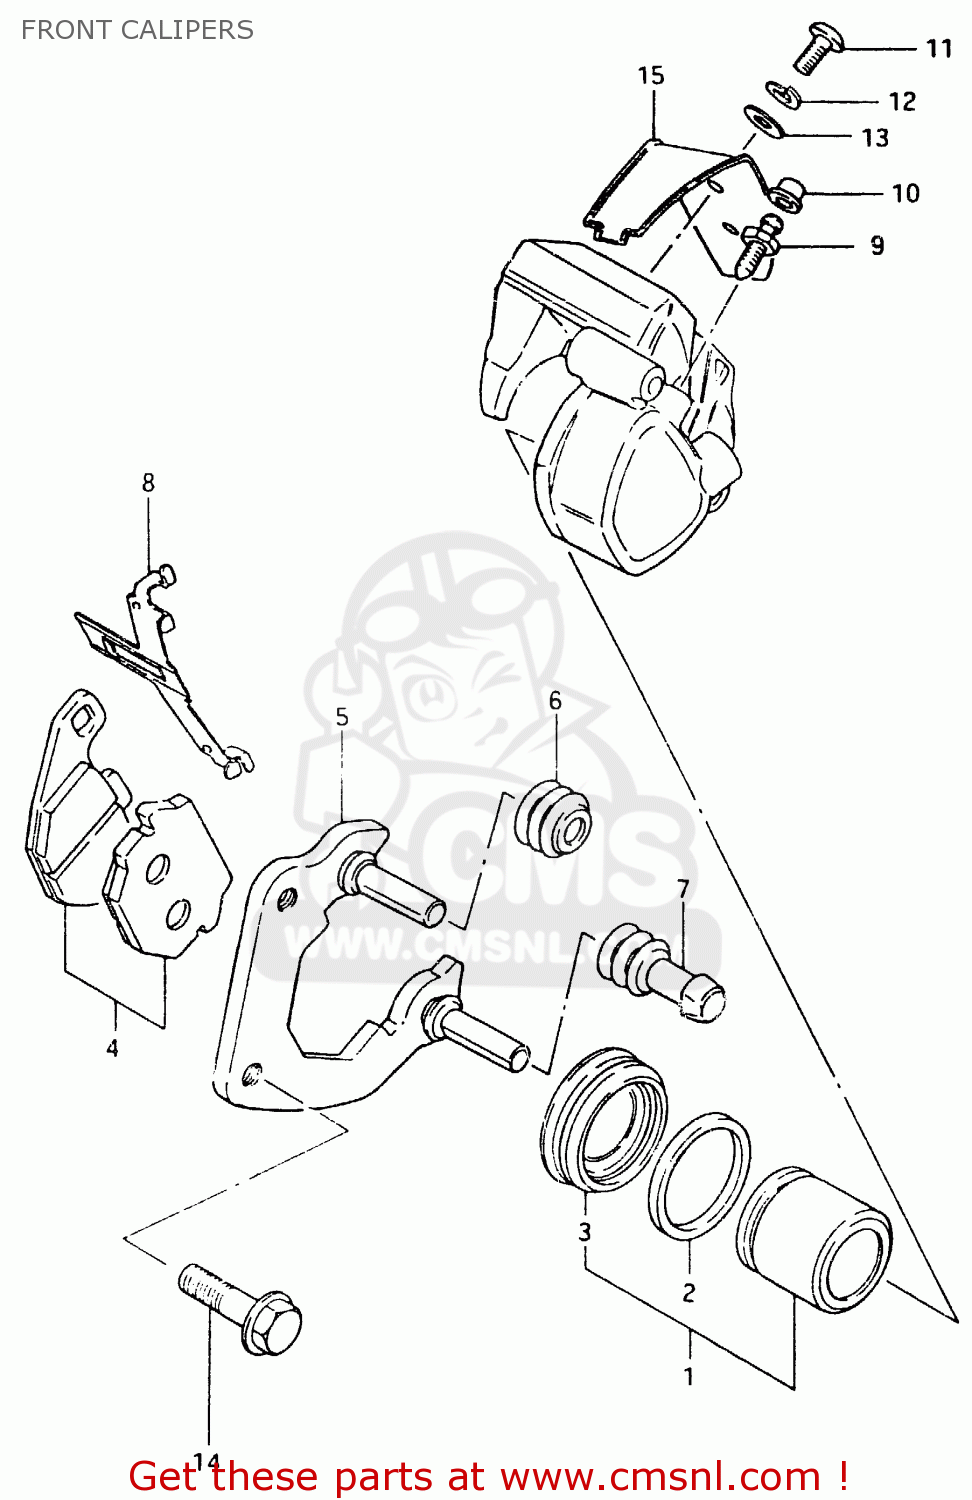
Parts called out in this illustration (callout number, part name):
1	PISTON SET
2	SEAL,PISTON
3	BOOT,PISTON
4	PAD SET,BRAKE (MCA)
5	CARRIER,CALIPE
6	BOOT,AXLE
7	INSULATOR,AXLE
8	SPRING,PAD
9	BLEEDER
10	CAP,BREATHER
11	SCREW
12	LOCK WASHER
13	WASHER
14	BOLT
15	PROTECTOR,CALIPER
